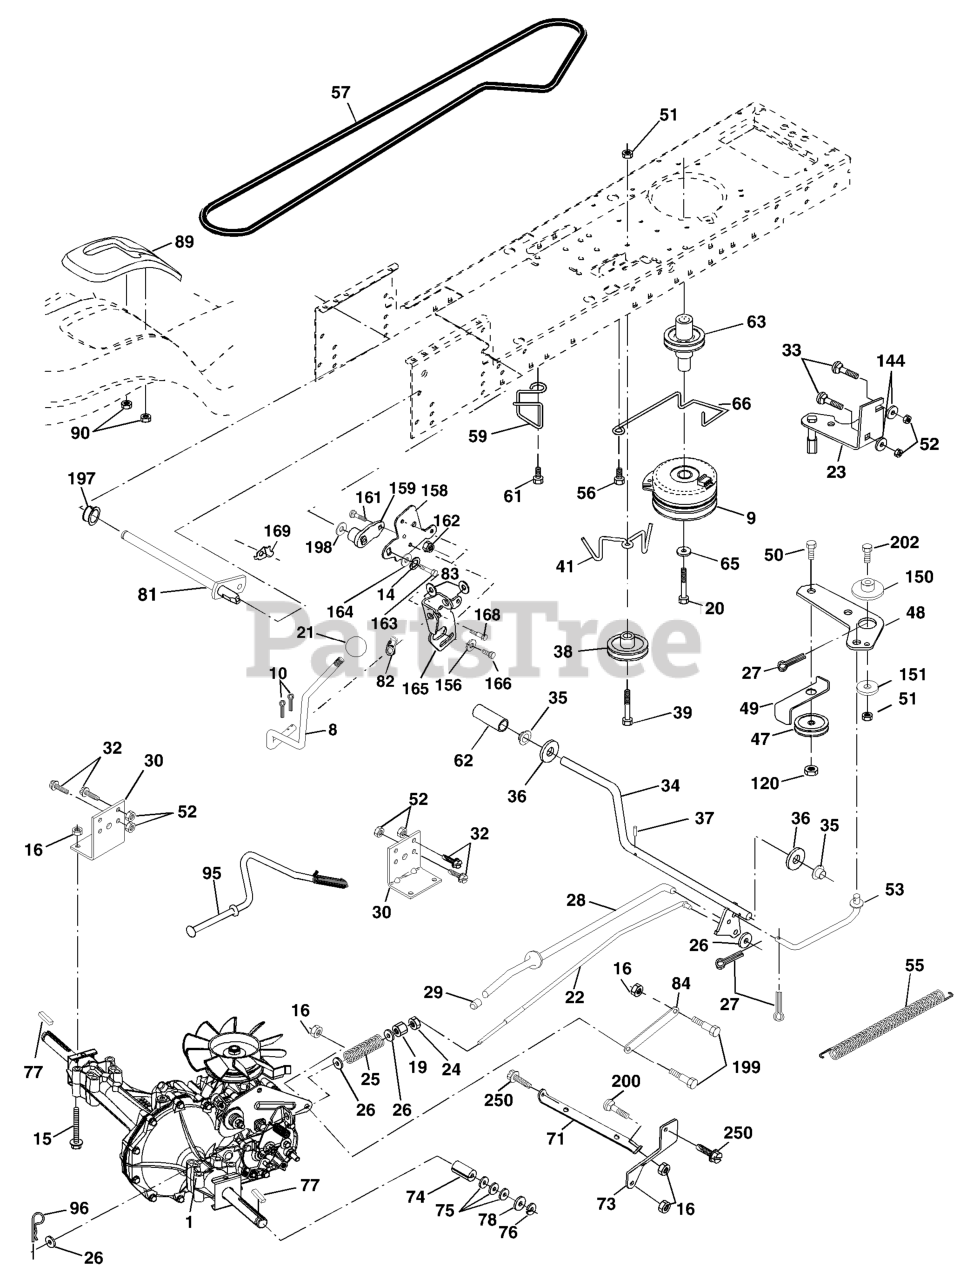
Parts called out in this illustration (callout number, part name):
8	ROD SHIFT FENDER ADJUST STLT
9	ELECTRIC CLUTCH
10	PIN COTTER
14	LOCKWASHER
15	BOLT HEX 5/16-18 GR 5
16	NUT.71038.31-18.HEX.NYLOCK
19	NUT
20	BOLT HEX
21	KNOB.DELUXE.(PISTOL.GRIP).BLAC
22	ROD BRAKE HYDRO
24	NUT
25	SPRING ROD LT
26	WASHER
27	COTTER PIN
28	ROD, PARKING BRAKE
29	PLUNGER CAP
30	BRKT, TRNSXLE MNT 20"
32	BOLT
33	RP BOLT 5/16-18 X3/4 ZN/YEL GR
34	SHAFT, FOOT PEDAL
35	BEARING.NYLON
36	WASHER LT
37	DRIVE PIN
38	PULLEY IDLER COMPOSITE
39	BOLT
41	KEEPER, BELT IDLER
47	IDLER PULLEY
48	BELLCRANK, CLUTCH
49	RETAIN BELT
50	BOLT
52	LOCKNUT
53	LINK, CLUTCH LT
55	SPRING, RETURN LT
56	SCREW.3/8-16
57	DRIVE BELT, LTH & YTH TRACTORS
59	KEEPER, BELT CENTER
61	SCREW 3/8-16X.875
62	PEDAL COVER T
63	PULLEY, ENGINE
65	LOCKWASHER
66	KEEPER BELT ENGINE
71	STRAP TORQUE LH HYDRO
73	STRAP TORQUE RH HYDRO
74	SPACER AXLE
77	SQUARE KEY
81	SHAFT ASM CROSS TAPERED
82	SHIFT SPRING
83	WASHER
84	LINK TRANSAXLE
89	SHIFT CONSOLE
90	NUT.PUSH.3/16
95	CONTROL ASM. BYPASS HYDRO
96	RETAINER M
120	NUT LOCK FLG 3/8-16 UNC
144	Washer 11/32 x 5/8 x 16 Ga.
150	SPACER, RETAINER
151	WASHER 12/32X2X10GA
156	WASHER.SRRTD.5/16
158	BRACKET
159	HUB
161	BOLT
162	NUT.CROWNLOCK.1/4
163	BOLT
164	Washer 5/8 x .281 x 10 Ga
165	RP BRACKET
168	BOLT.SHOULDER.5/16-18X
169	PLATE.FASTENING.CROSS.SHAFT
197	NYLINER SNAP 5/8" ID
198	WASHER.NYL.7/8IDX.105"HYD CR
199	BOLT SHOULDER 5/16-18 UNC
200	BOLT
250	SCREW 3/8-16X3/4
